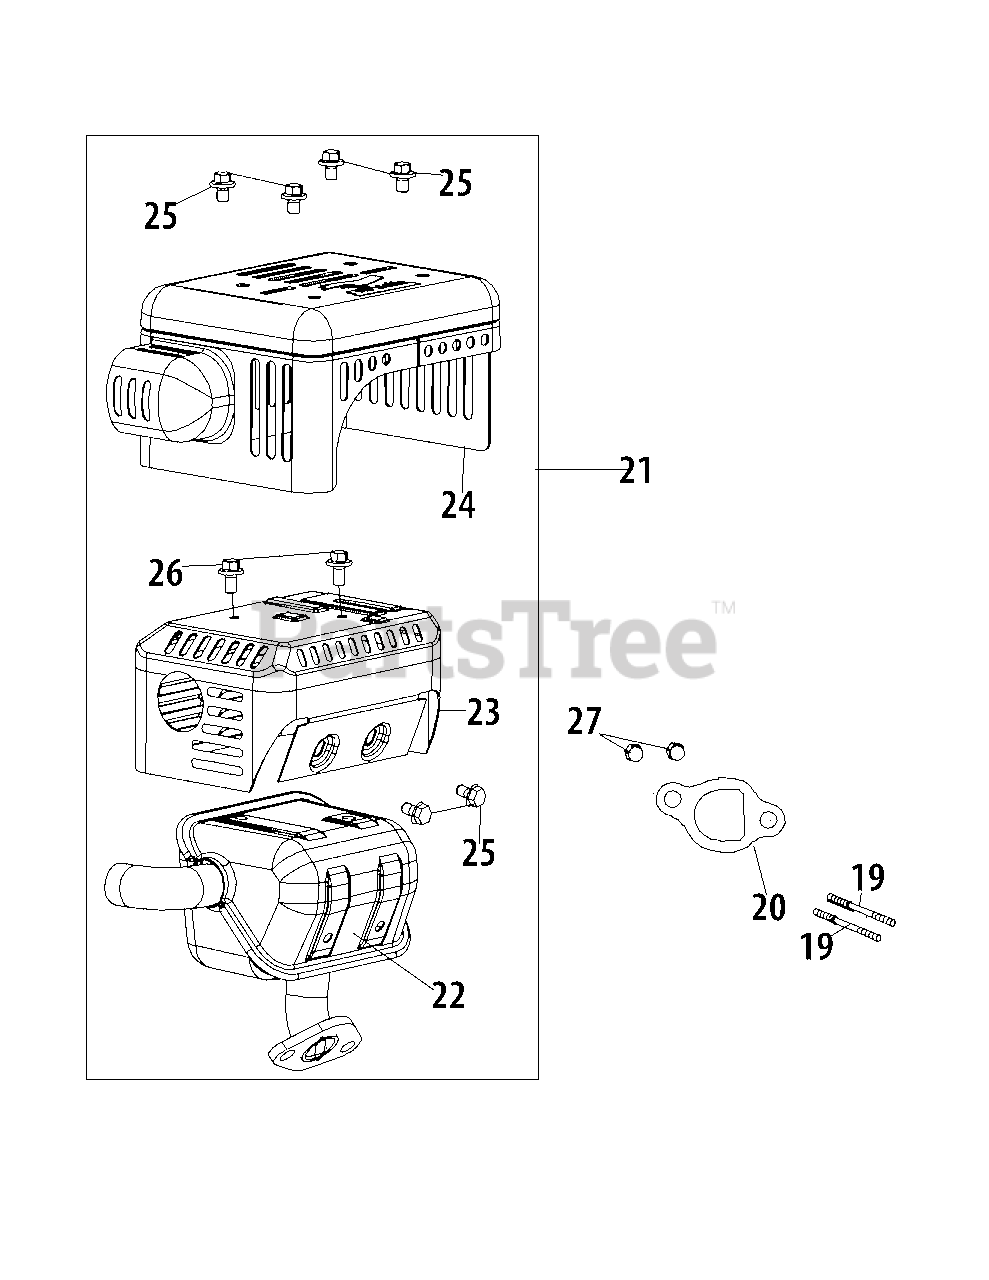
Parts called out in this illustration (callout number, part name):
19	Stud M8×34
19	Muffler Stud Assy
20	Exhaust Pipe Gasket
21	Muffler Assembly
22	Muffler Body
23	Muffler Shield
24	Muffler Guard
25	Bolt M5×8
26	Bolt M5×12
27	Nut,M8
